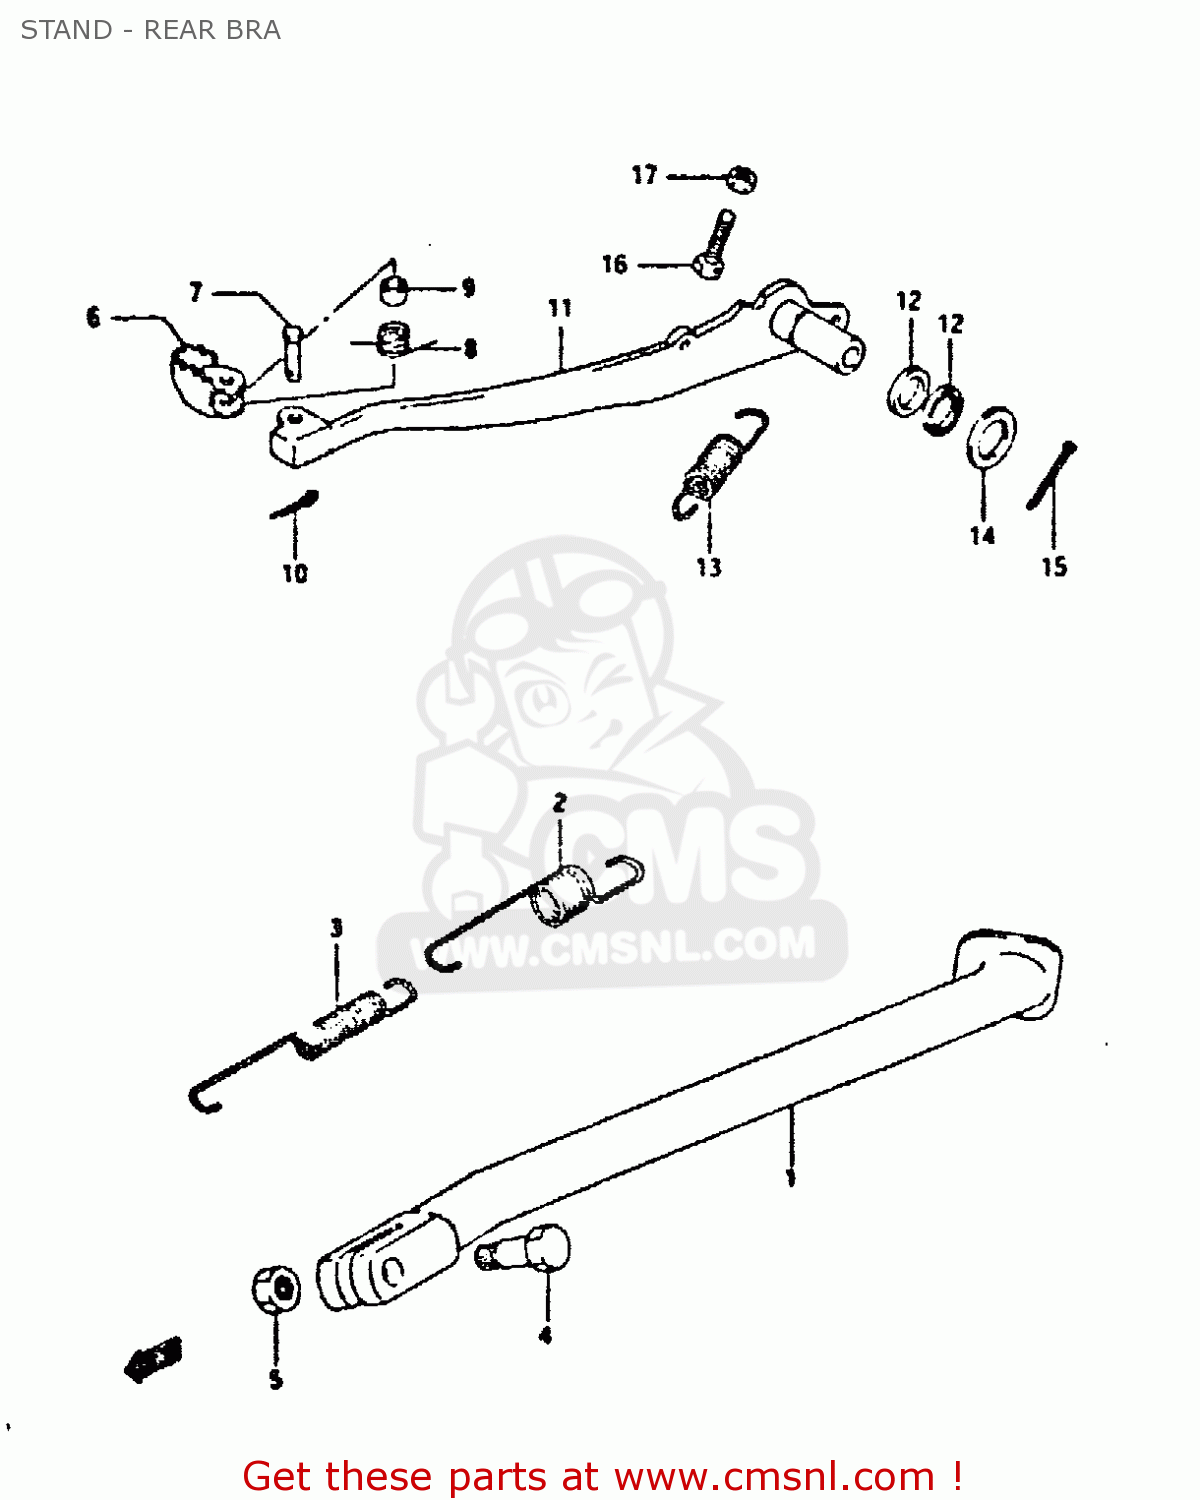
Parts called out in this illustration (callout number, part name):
1	STAND,SIDE
2	SPRING
3	SPRING
4	BOLT(10X30)
5	NUT
6	PEDAL,BRAKE
7	PIN
8	SPRING
9	SPACER(9.2X9X6.5)
10	PIN
11	ARM,BRAKE PEDAL
12	SEAL,OIL(15X21X3)
13	SPRING
14	WASHER(15.5X26X2.3)
15	COTTER PIN
16	BOLT(6X23)
17	NUT
